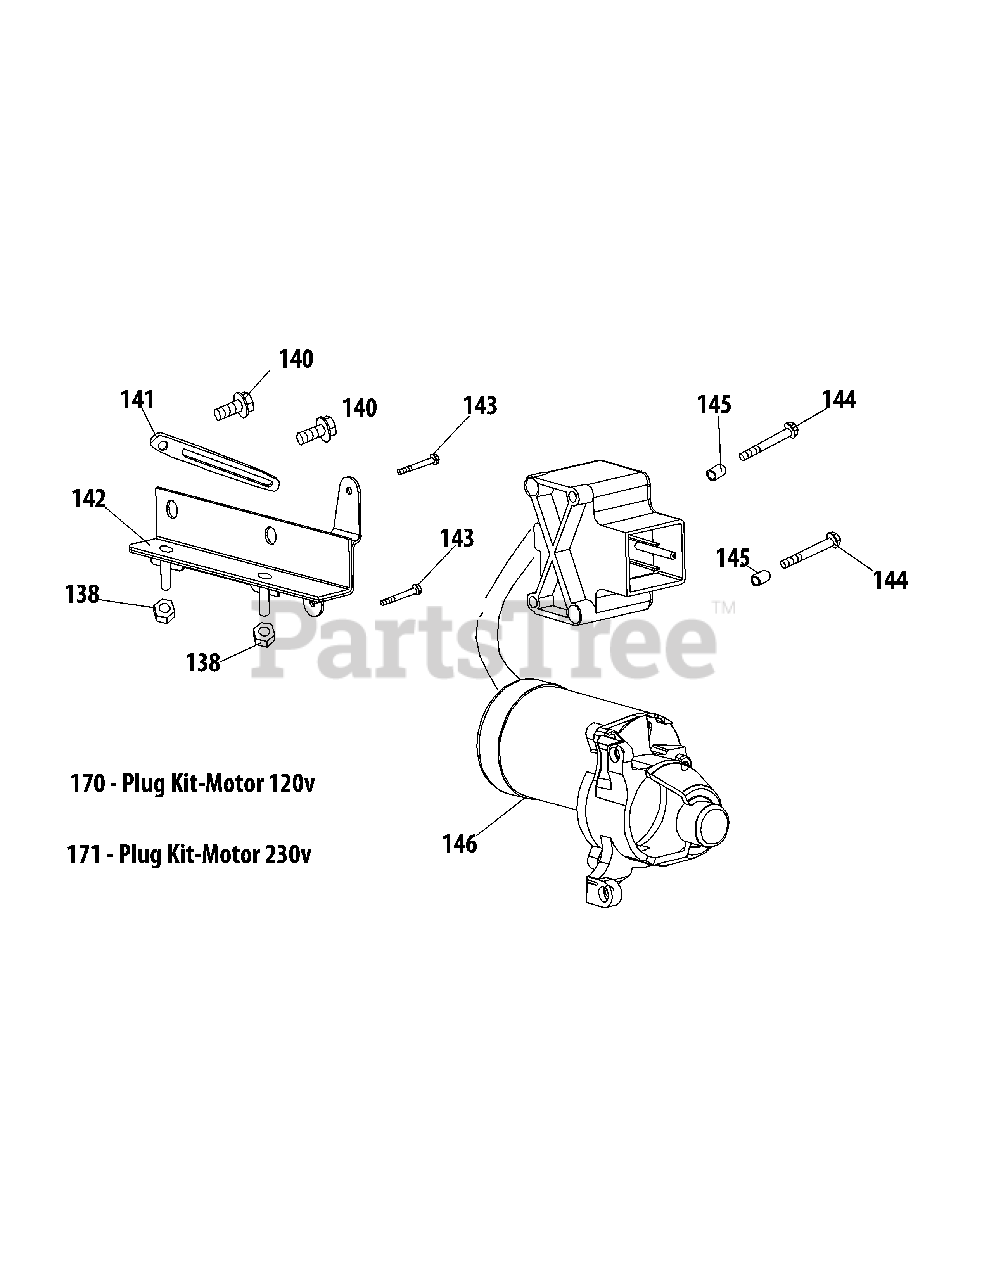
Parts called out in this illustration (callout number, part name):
140	Bolt M6×10
141	Electric Starter Cord Retainer
142	Switch Housing Mounting Bracket
143	Bolt M4×55
144	Bolt M6×32
145	Dowel Pin 8×8
146	Electric Starter
170	Plug Kit-Motor 120v
